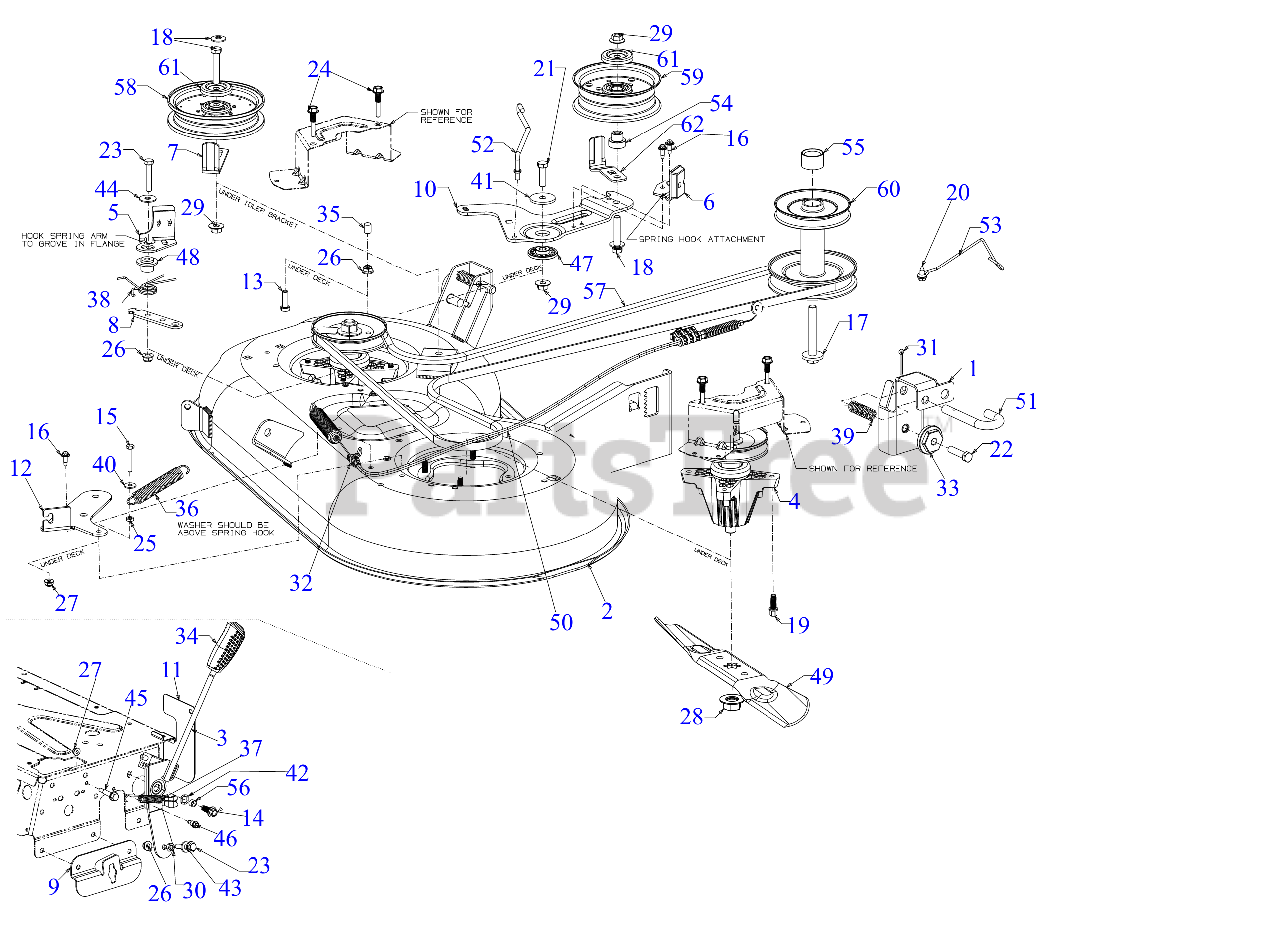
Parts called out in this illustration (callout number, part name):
4	SPINDLE ASSEMBLY
5	DECK BRAKE ASSEMBLY
6	DECK BRAKE ASSEMBLY
10	IDLER PIVOT BRACKET
13	SCREW 5/16-18 x 1.0 GR5
14	SCREW 3/8-16 x 1
15	SCREW 1/4-20 x 1.50 GR8
16	SCREW M6-1 x .625
17	SCREW-SEMS 7/16-20 x 3.25 PATCH
18	SCREW 3/8-16 x 2.0
19	SCREW 5/16-18 x .875
20	SCREW 1/4-20X.625
21	SCREW 3/8-16 x 1.25 GR5
22	SCREW 3/8-16X1.5 GR5
23	SCREW 5/16-18 x 1.75 GR5
24	BELT KEEPER ROD .25 x 1.585
25	HEX JAM NUT 1/4-20
26	FLANGE LOCK NUT 5/16-18
27	FLANGE LOCK NUT
28	HEX NUT
29	FLANGE LOCK NUT
30	HEX NUT 5/16-18
31	COTTER PIN-5/32 DIA
32	BOW TIE COTTER PIN
33	DECK ADJUSTMENT GEAR
35	VINYL CAP
36	EXTENSION SPRING
37	EXTENSION SPRING .56 OD x 4.52
38	TORSION SPRING
39	COMPRESSION SPRING .66 OD x 1
40	FLAT WASHER .28 ID x .74 OD x .063
41	FLAT WASHER
42	WAVE WASHER
43	FLAT WASHER.344X.75X.1
44	FLAT WASHER 344X1.00
45	SHOULDER SCREW
46	SHOULDER SCREW
47	SHOULDER SPACER
48	DOUBLE SHOULDER SPACER .750 x .135
49	17.27" BLADE (2N1)
49	Cub Cadet 50" HI LIFT BLADE SET
49	Genuine Factory Parts 50" BLADE SET
49	50" 6 PT STAR LOW LIFT/SAND BLADE
49	Cub Cadet 50" LOWLIFT BLADE SET
49	Genuine Factory Parts 50" LOWLIFT BLADE SET
49	50" 6 PT STAR XTREME MULCH BLADE
49	Cub Cadet 50" XTREME BLADE SET
49	Genuine Factory Parts 50" XTREME MULCH BLADE SET
50	PTO CABLE
51	DECK RELEASE PIN
52	DECK BRAKE ROD (RH)
53	PTO CABLE GUIDE
54	SHOULDER SPACER
55	ENGINE PULLEY SPACER
56	SPACER
57	V-TYPE BELT A SEC x 111.1
58	FLAT IDLER PULLEY
59	IDLER PULLEY 4.50" DIA
60	MANUAL PTO ENGINE PULLEY
61	IDLER PULLEY CAP
